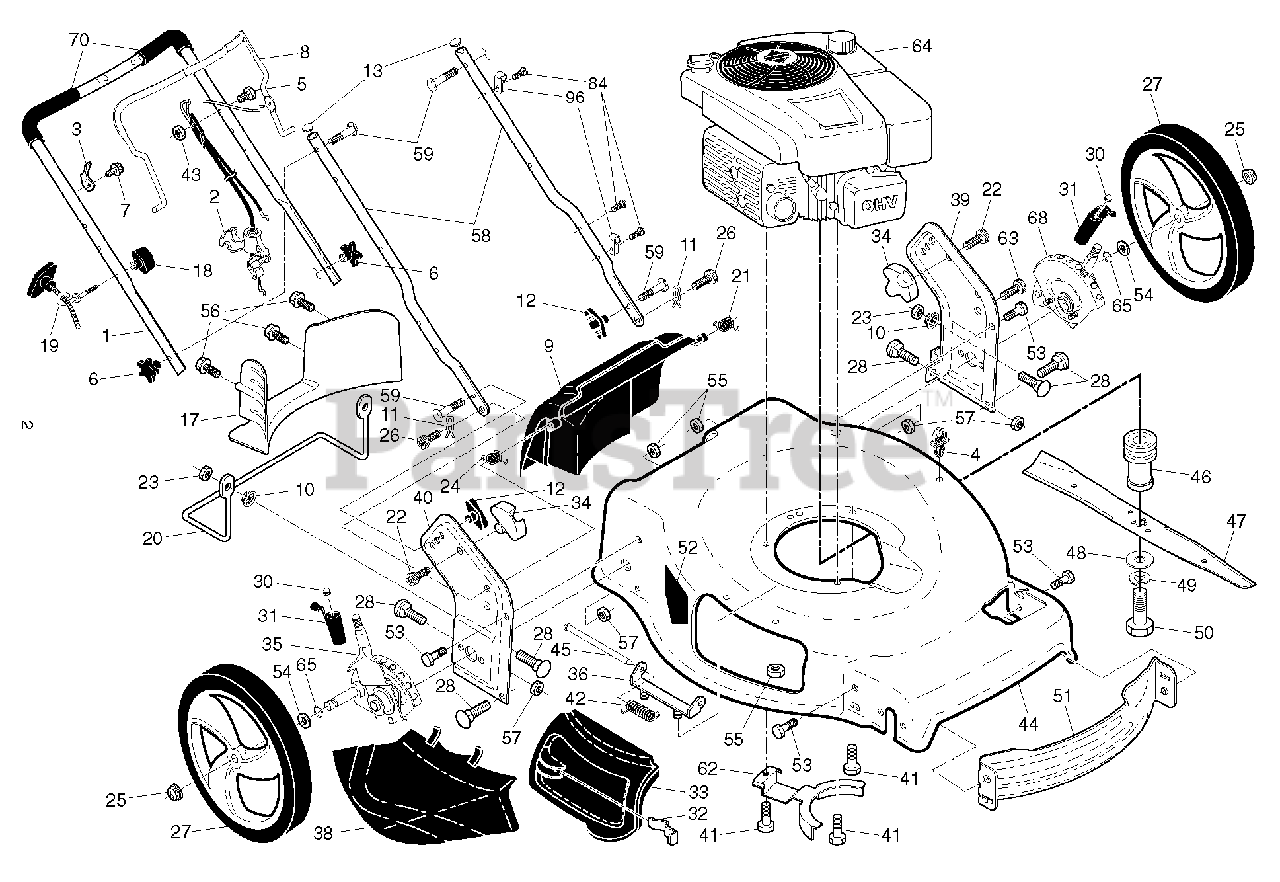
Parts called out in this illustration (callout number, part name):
1	HANDLE.ASM.UP.BS.AW2.GRIP.479
2	CABLE.ASM.MZR/DP.B&S PRO.FGD
3	BRACKET.UPSTOP.RT
4	PUSH CLIP
6	KNOB.HANDLE.PLASTIC.STAR.BLACK
11	COTTER.HAIRPIN.DOOR/HANDLE.PIV
12	KNOB, DEFLECTOR
13	PLUG.PLASTIC.7/8".14-20.GAUGE
18	T-Knob, New Rope Guide
19	Rope Guide, Blk Zinc Chrom
21	SPRING.LH.GRAY
22	SCREW.PAN.HEAD.#10
23	LOCKNUT-FLANGE 5/16-18
24	SPRING.RH.GRAY
25	NUT.HEX.FLANGE.3/8-16.LOCKNUT
26	SCREW,DOOR/HANDLE.PIVOT
28	Carriage Bolt, 5/16-18 X 5/8
32	LATCH.DOOR.ZINC
36	HINGE BRACKET ASSEMBLY
38	DEFLECTOR.CLIPPING.22.BLACK
39	Handle Bracket Assembly, LH 22+ Black
40	Handle Bracket Assembly, RH 22+ Black
41	BOLT 3/8-16X1-1/8
42	SPRING.TORSION
43	NUT
44	KIT.HSG.22+.FGD.MC.WO.CE.MS667
45	ROD.HINGE.21
46	Blade Adapter, 25mm Star
47	BLADE.22+4N1.2PIN.5STAR.
48	WASHER,HARDEN
49	LOCKWASHER
50	SCREW, HEX HD 3/8-24 X 1-3/8
52	DECAL.INTERNATIONL.CUTFINGER
53	BOLT.5/16HEX.WHS.HD
54	WASHER PM
55	NUT.HEX.FLANGE.1/4
56	SCREW.HX.13X.750
57	NUT.FLANGE.5/16
58	HANDLE.LOWER.22+.BT.2PC.BLK
59	BOLT, HANDLE 5/16-18X1.75
62	BRACKET.ENG/BELTKEEPER
65	O-RING..070X.487.NEOPRENE
70	GRIP.HDL.FOAM.WIDE.2PC.222MM
84	FASTENER.PUSH.O.250X0.783
96	CLIP.CABLE.BLK
